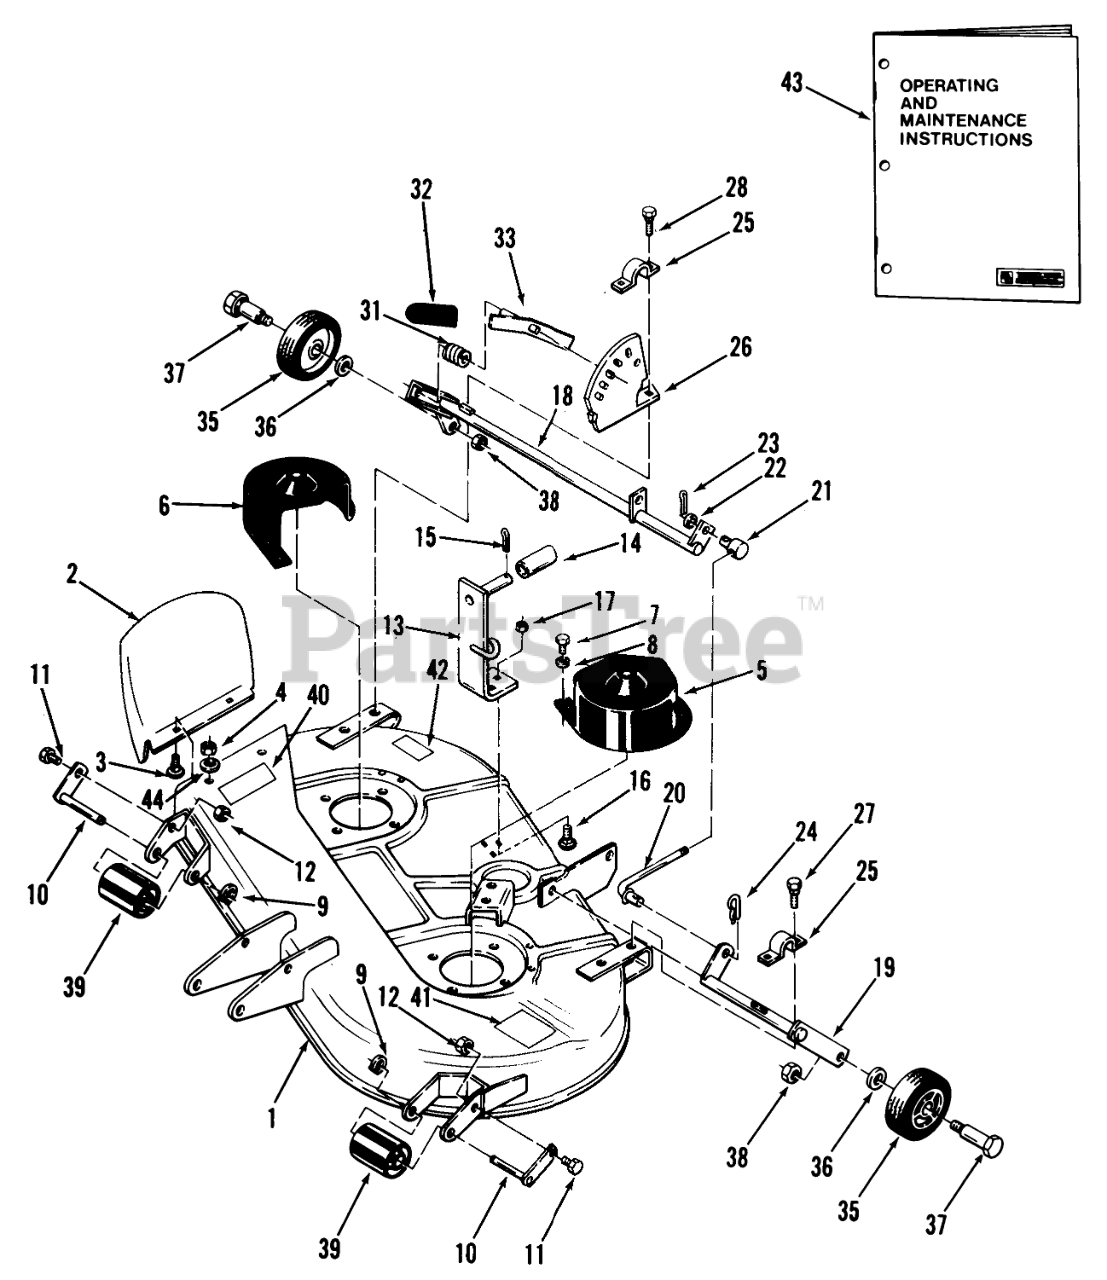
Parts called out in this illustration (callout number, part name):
1	Mower Deck
2	Chute Extension
3	CARRIAGE BOLT -4
4	Nut
5	Belt Cover LH
6	Belt Cover RH
7	Bolt
8	WASHER
9	Retaining Ring
10	Roller Shaft
11	H H C S
12	Nut
13	Bracket Guide
14	SPACER
16	BOLT HEX SPECIAL
17	Nut
18	Gage Wheel Support RH
19	WA GAG WHL R
20	Rod
21	TRUNNION
22	Washer
23	Pop Rivet
24	Hairpin
25	CLAMP
26	Quadrant
27	Bolt
28	Bolt
31	SPRING-COMPRESSION
33	Lever
35	Wheel 6 x 1.75
36	WASHER
37	BOLT-SHOULDER
38	Nut
39	Roller
40	DECAL
41	Caution Decal
42	DECAL-BELT&HEIGHT
43	Operating and Maintenance Instructions
44	WASHER 5/16 SAE
